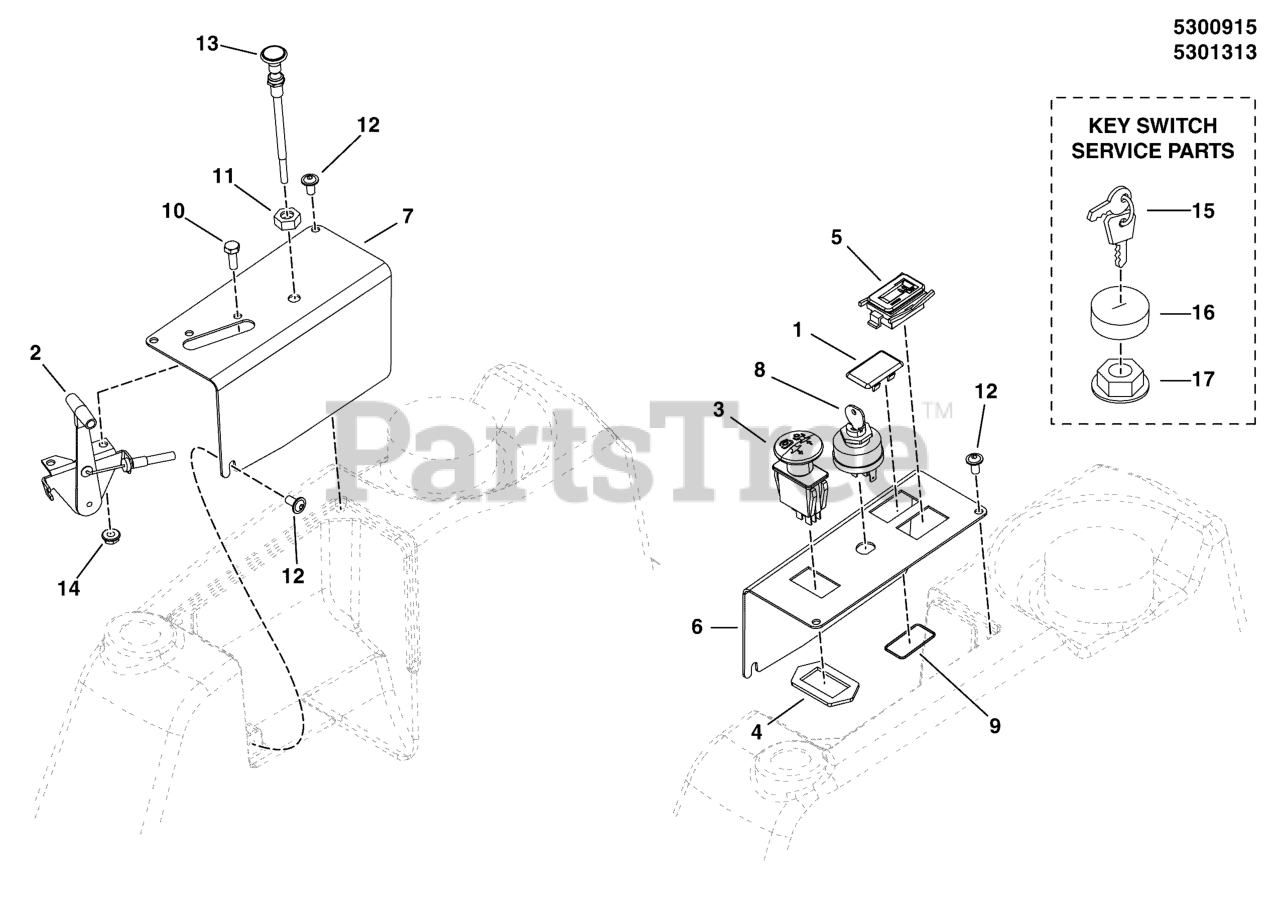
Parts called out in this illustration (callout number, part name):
1	PLUG, .820X1.44 HOLE, BLACK PLASTIC
2	CABLE, THROTTLE CONTROL, 38
3	SWITCH, BLADE ENGAGEMENT
4	RING, SWITCH RETAINER
5	* HOUR METER, ASSEMBLY
5	HOUR METER
6	CONTROL PANEL, LEFT - BLK
7	CONTROL PANEL, RIGHT - BLK
8	SWITCH, IGNITION, 6 POST
9	O-RING, 7/8" ID X 1/16" W
10	HHCS, 1/4-20 X 0.625, GR5, ZINC/CLEAR
11	NUT, 3/8-24 Hex Jam
12	SCREW, ALLEN HEAD 1/4-20X.500 ZINC PHOS
13	CABLE, CHOKE CONTROL, 39.5"
13	CABLE, CHOKE CONTROL, 35.25"
14	NUT, 1/4-20 Hex Nylock Flange
15	KEY, IGNITION MOLDED SET
16	COVER, PLASTIC, SNAP ON
17	PLASTIC NUT
